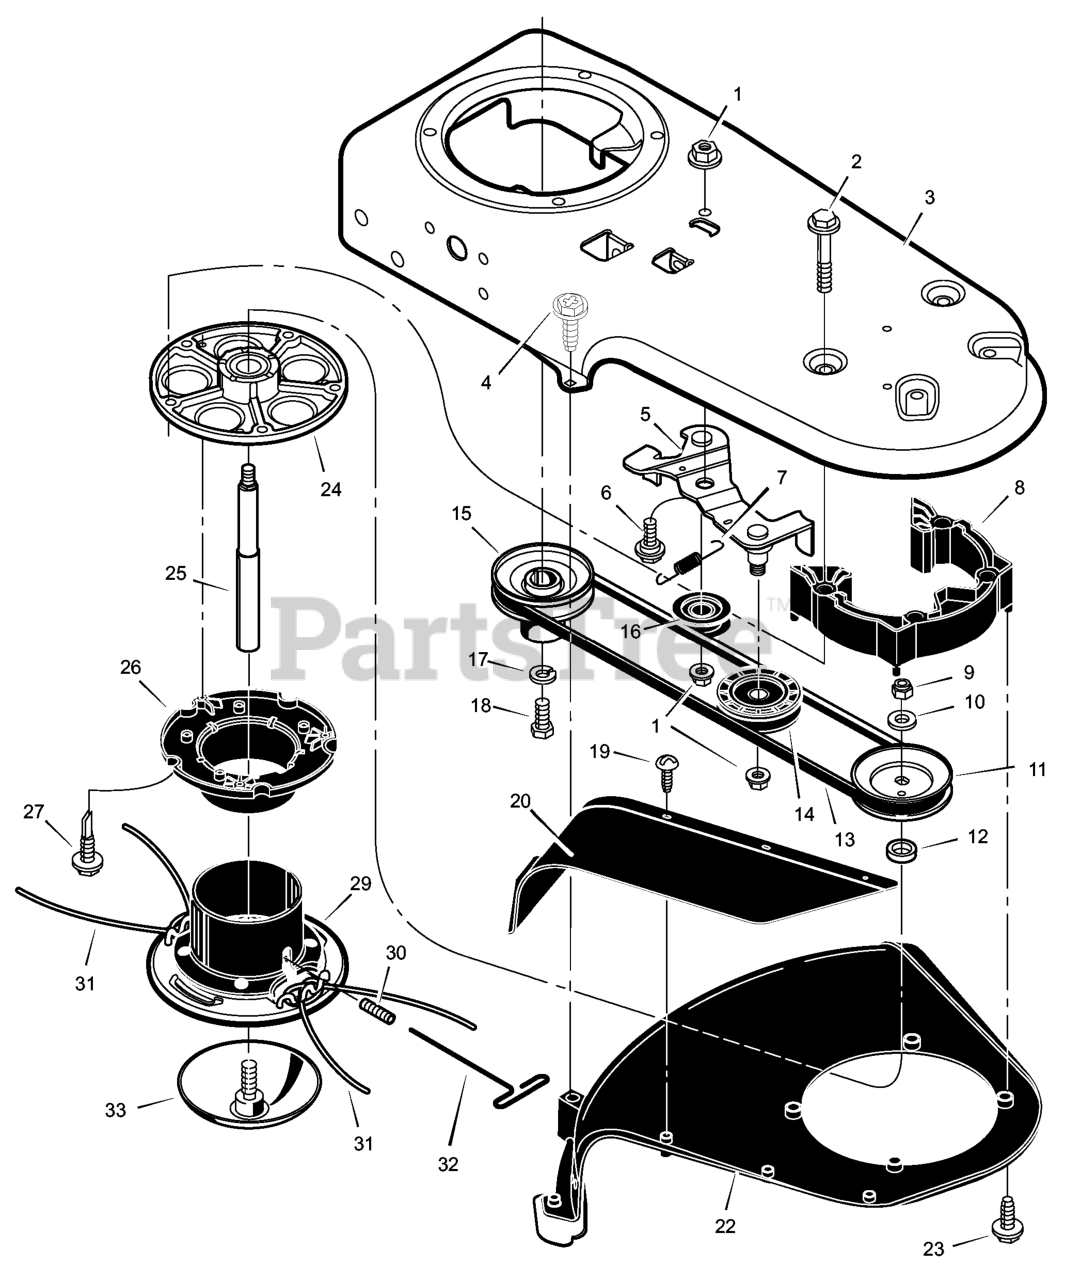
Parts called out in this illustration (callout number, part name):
1	Nut
3	Frame, Trimmer
5	Bracket, Idler Assembly
7	Spring, Extension
8	Spacer Assembly, Jackshaft
10	Washer, Flat
11	Pulley, Cutting Head
12	Spacer, Upper Pulley
13	Belt, Trimmer
14	PULLEY, IDLER, V, 1.88
15	Pulley, Engine
16	Pulley, Idler
17	Lockwasher
20	Flap, Depris
22	Shield, Trimmer
24	Housing, Jackshaft
25	Shaft, Cutting Head
26	Wrap, Weed
29	Assembly, Cutter Head & Wrap
31	Line, Trimmer 0.155 X 21.25
32	Wrench, T-Handle
33	Guide Assembly, Height
